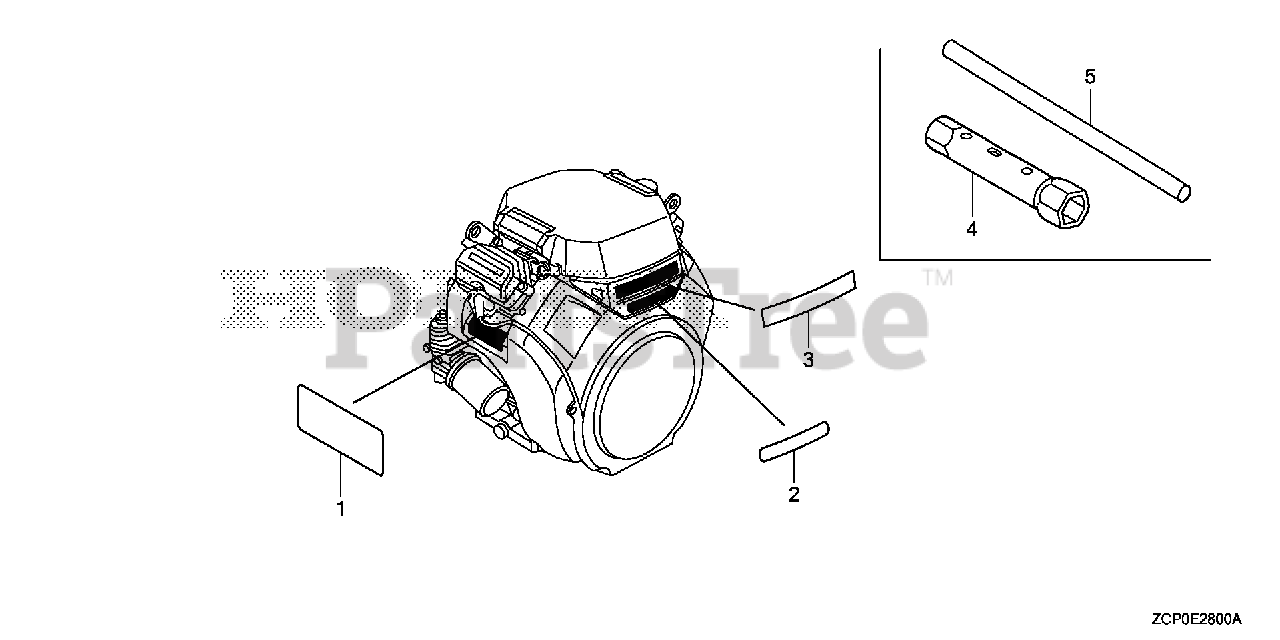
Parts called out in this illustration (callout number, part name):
1	MARK, OPERATOR CAUTION (ENGLISH)(MADE IN CHINA)
2	EMBLEM (GX690)
3	MARK, HONDA
